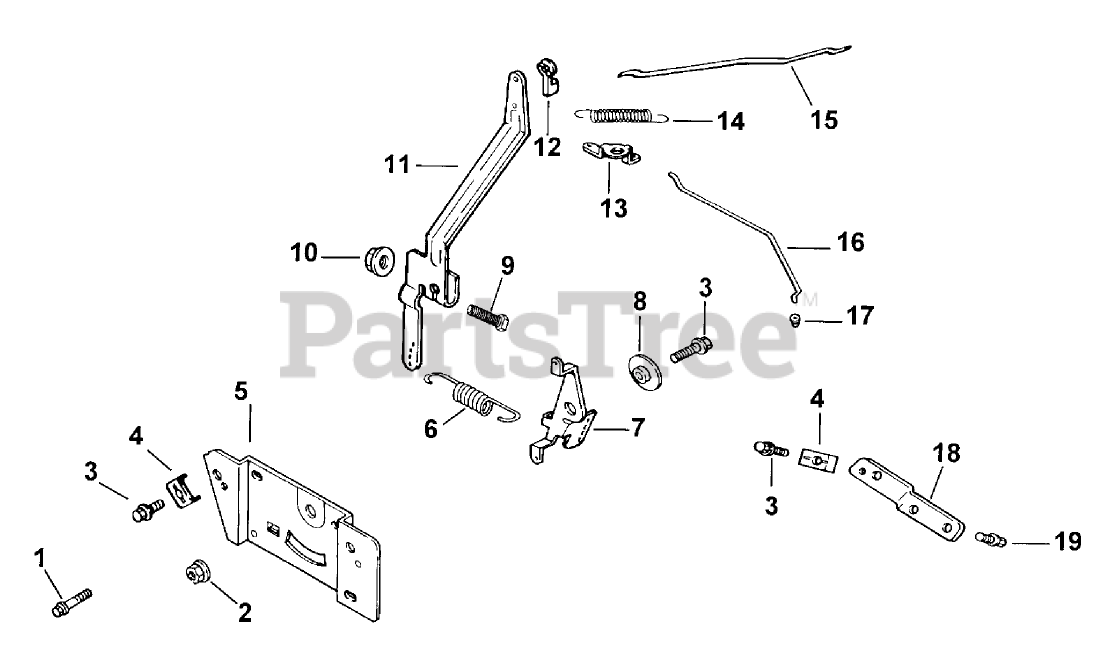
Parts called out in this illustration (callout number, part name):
1	Screw Socket
2	Nut, hex. flange M5x0.8
3	Screw M5x0.8x16 (Only On: 72042, 72063, 72062, 72043)
4	Clamp
5	Plate, control
6	Spring, governor
7	Lever, throttle control
8	Spacer, throttle control
9	Screw
10	Nut
11	Lever, governor
12	Bushing-Linkage
13	Lever, choke-upper
14	Spring, linkage
15	Linkage, throttle
16	Linkage, choke-upper
17	Bushing
18	Bracket, choke mount
19	Screw
